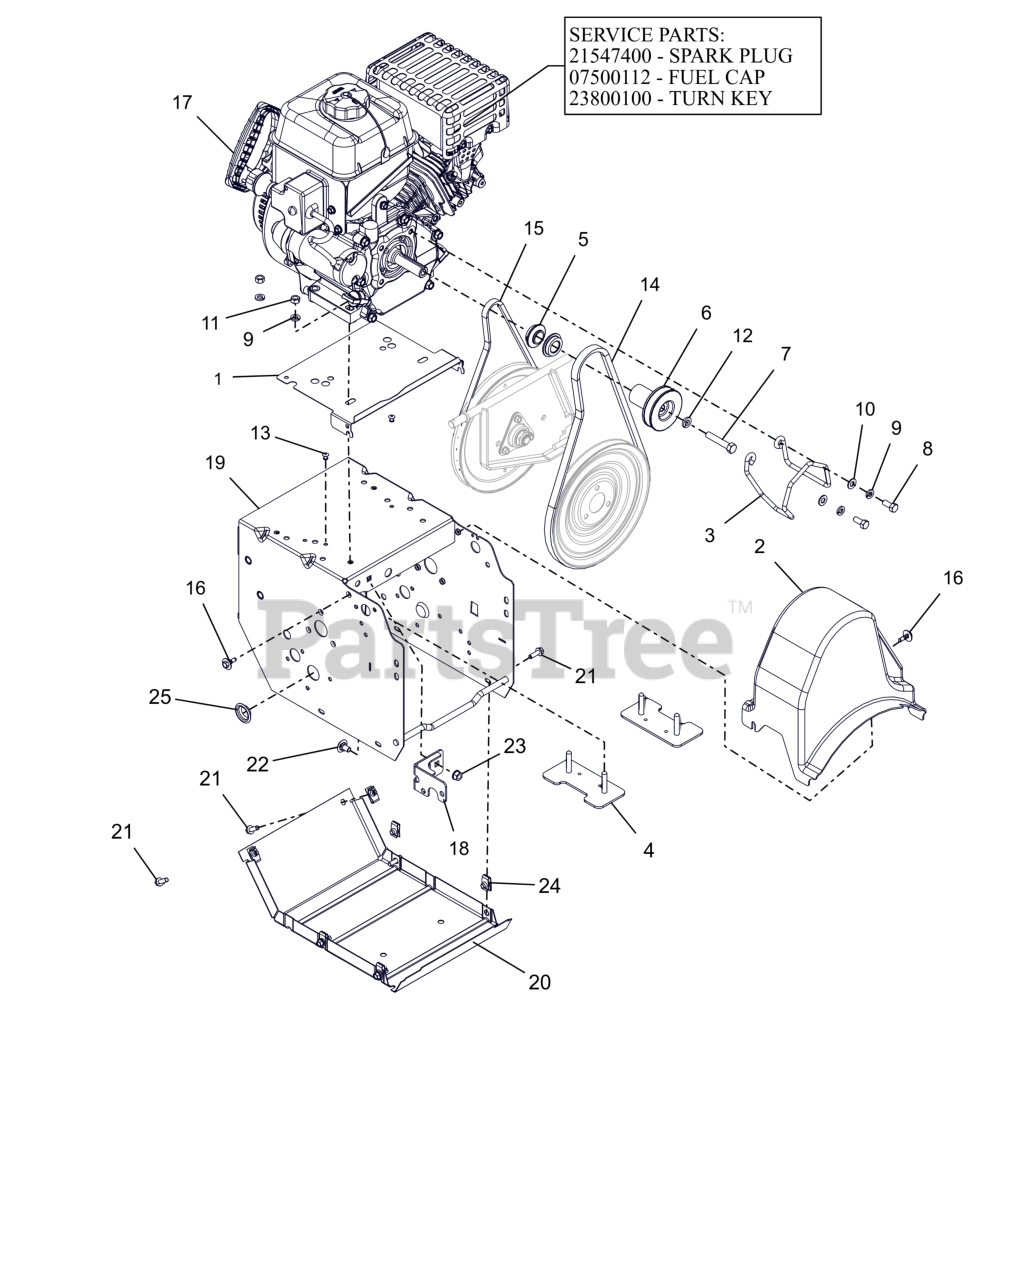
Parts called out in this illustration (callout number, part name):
1	BAFFLE, COMPACT
2	COVER, COMPACT BELT
3	FINGER, BELT
4	STRAP, ENGINE BOLT-WELDMENT
5	SHEAVE, TRACTION HALF (KEYLESS)
6	SHEAVE, AUGER 3/4 - PM
7	BLT, HEX .38-24X2.00 G5 ZCC
8	BLT, HEX .31-24X.750 G5 ZCC
9	WSHR, LK-HVY .312X.097 ZCC
10	WSHR,FLT .344X.688X.065 ZCC
11	NUT, HEX .312-18 ZCC
12	WSHR, LK-HVY .375X.115 ZCC
13	RVT, POP .1875 ZCC
14	V-BELT, HA-RAW EDGE
15	V-BELT, 3L-WRAPPED
16	SCR-TAP .25-20X.5 CAPTIVE
17	ENGINE, AX208 GEN 2 120V
17	ENGINE, ARIENS AX208 120V
17	ENGINE, SNO-TEK 208 120V
17	PLUG, SPARK
17	CAP, FUEL TANK BLACK
17	KEY, TURN LCT (2/PACKAGE)
18	WELDMENT, FRAME BRACKET
19	FRAME, MAIN
20	COVER, BOTTOM
21	BLT, HWH .25-20X.75 G5 ZCC
22	BLT, RHSSN .31-18X.625 G5 ZCC
23	NUT-LK-TOP-FLG .312-18 GF ZCC
24	NUT-RTNR .25-20X.56
25	PLUG, HOLE - 1.00" FLEXTEMP
